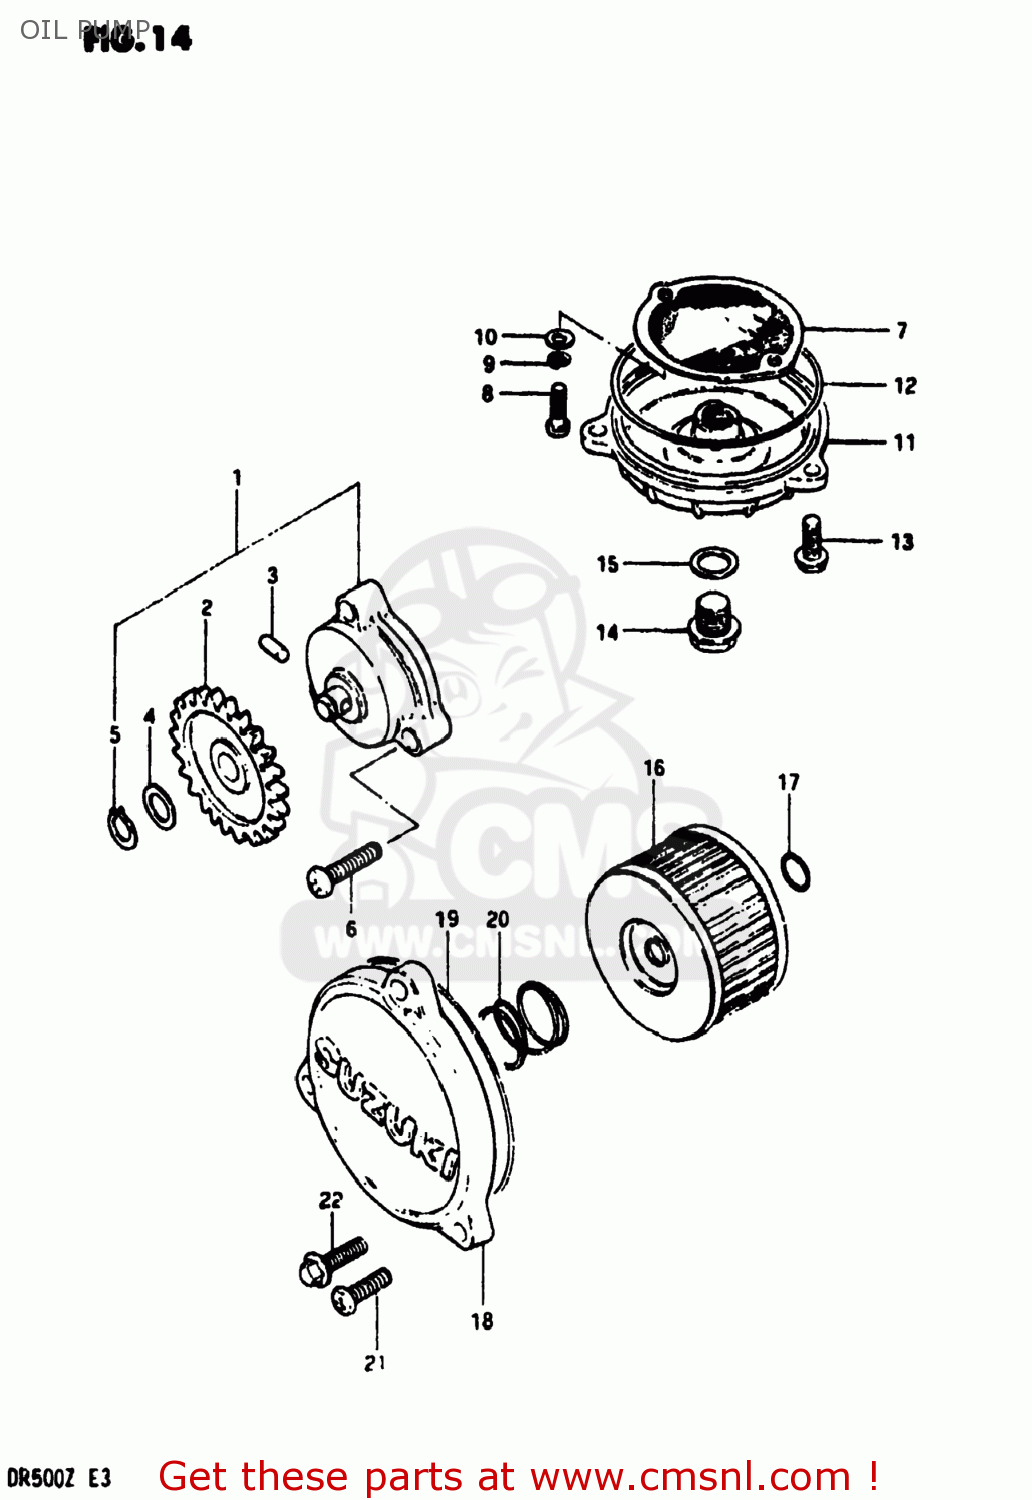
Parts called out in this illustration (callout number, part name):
1	PUMP ASSY,ENGINE OIL
2	GEAR,OIL PUMP DRIVEN
3	PIN(4X15.8)
4	SHIM
5	CIRCLIP
6	SCREW
7	STRAINER,ENGINE OIL
8	SCREW
9	LOCK WASHER
10	WASHER
11	CAP,OIL STRAINER
12	O RING(D:2.4,ID:85)
13	BOLT,REAR
14	PLUG (14X12)
15	GASKET(14X19.2X2) (NAS)
16	FILTER,ENGINE OIL
17	O RING(D:2.4,ID:15.8)
18	CAP,ENGINE OIL FILTER
19	O RING(D:2.4,ID:73)
20	SPRING
21	SCREW
22	BOLT (6X20)
